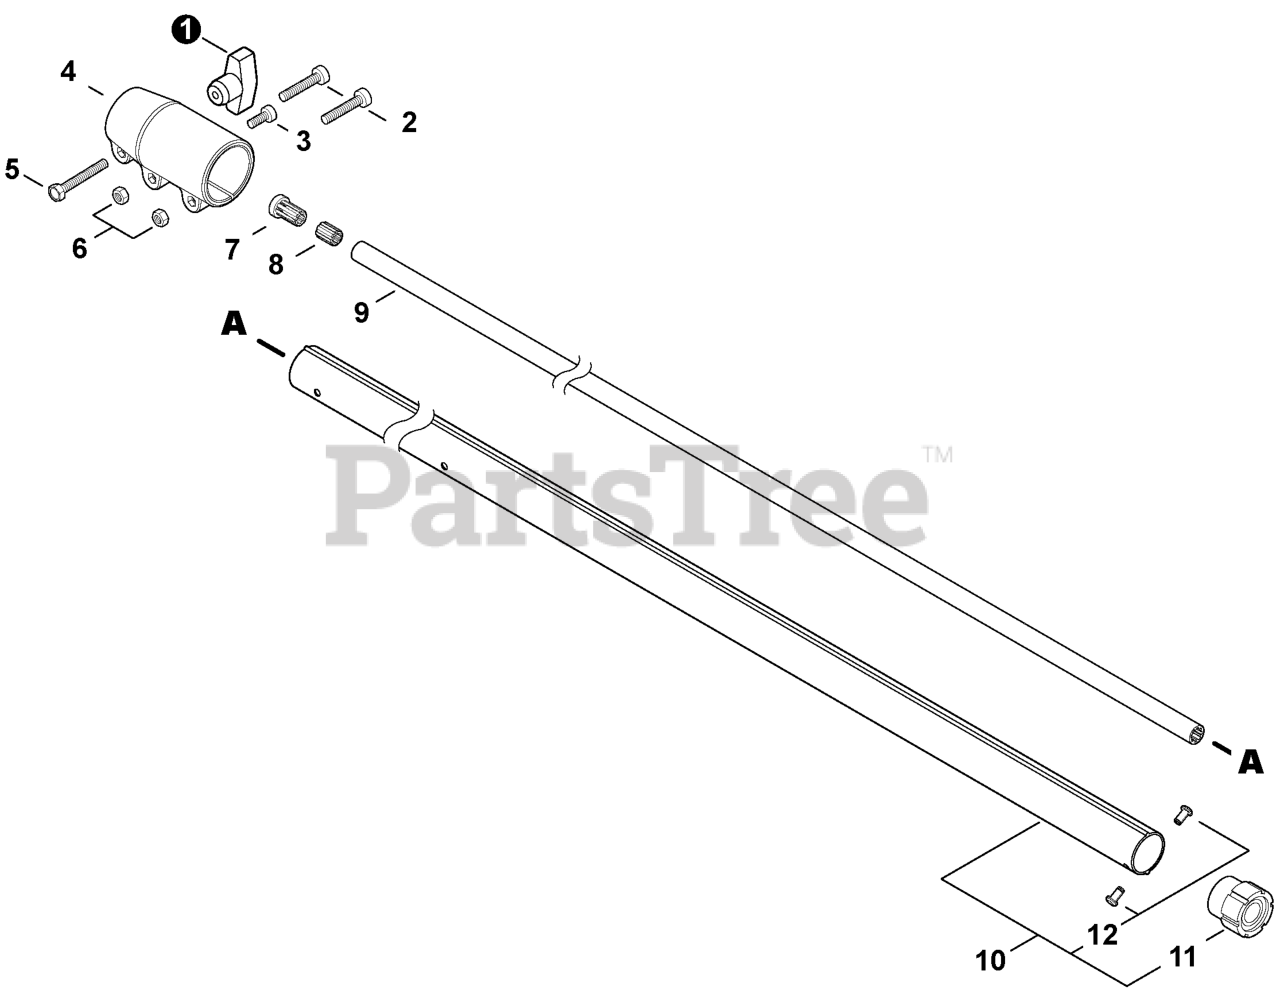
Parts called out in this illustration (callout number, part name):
1	THUMBSCREW
2	BOLT, TORX 5x20
3	BOLT, TORX 5x12
4	COUPLING, MAIN PIPE
5	BOLT 6x25
7	SOCKET - OUTER
8	SOCKET - INNER
9	DRIVESHAFT - UPPER
10	MAIN PIPE ASSY - BLACK
11	HOLDER ASSY, BEARING
